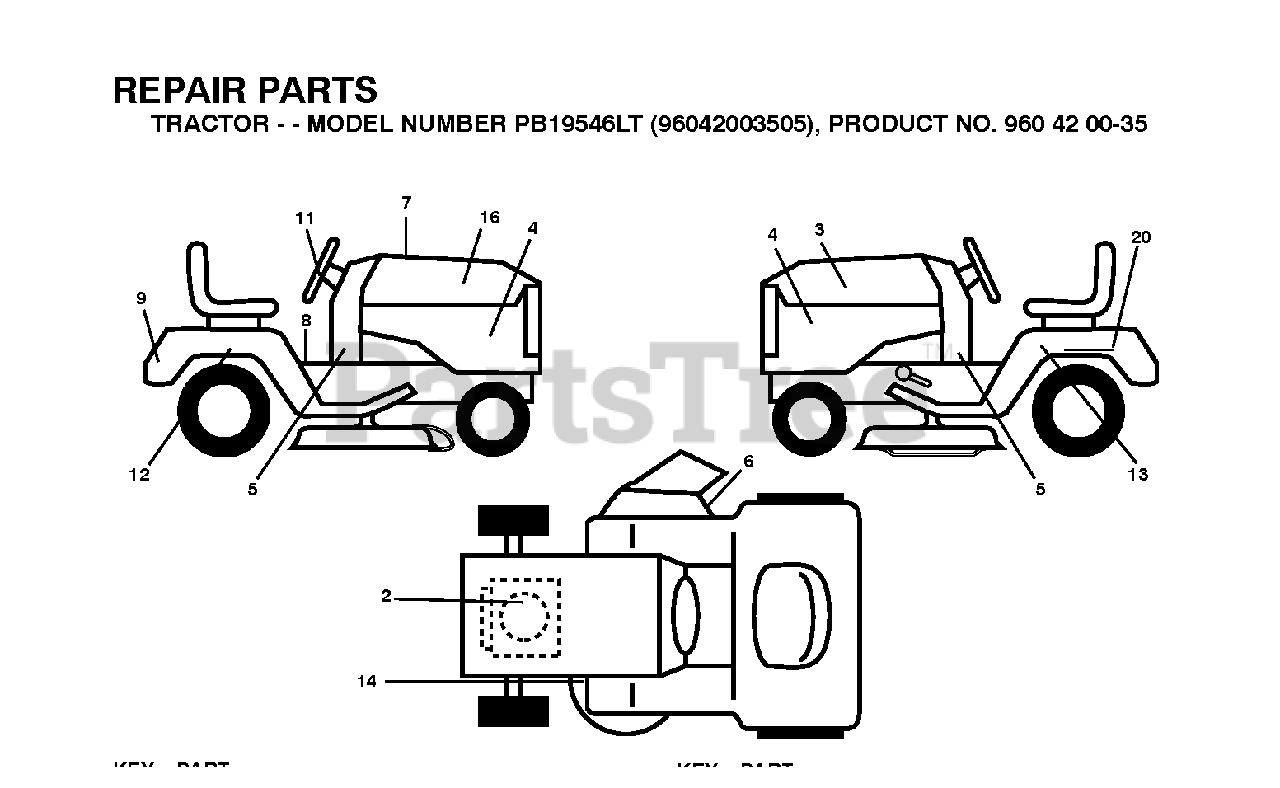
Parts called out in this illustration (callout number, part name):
2	DECAL.ENGINE.B&S.(278443)
6	DECAL.WARN.KEEP.HAND.AWAY
8	Fender Engine Warning Decal
9	DECAL.FEND.LOGO.POULAN.PRO
14	DECAL V BELT SCHEMATIC
20	DECAL BTRY SYMBOLS
